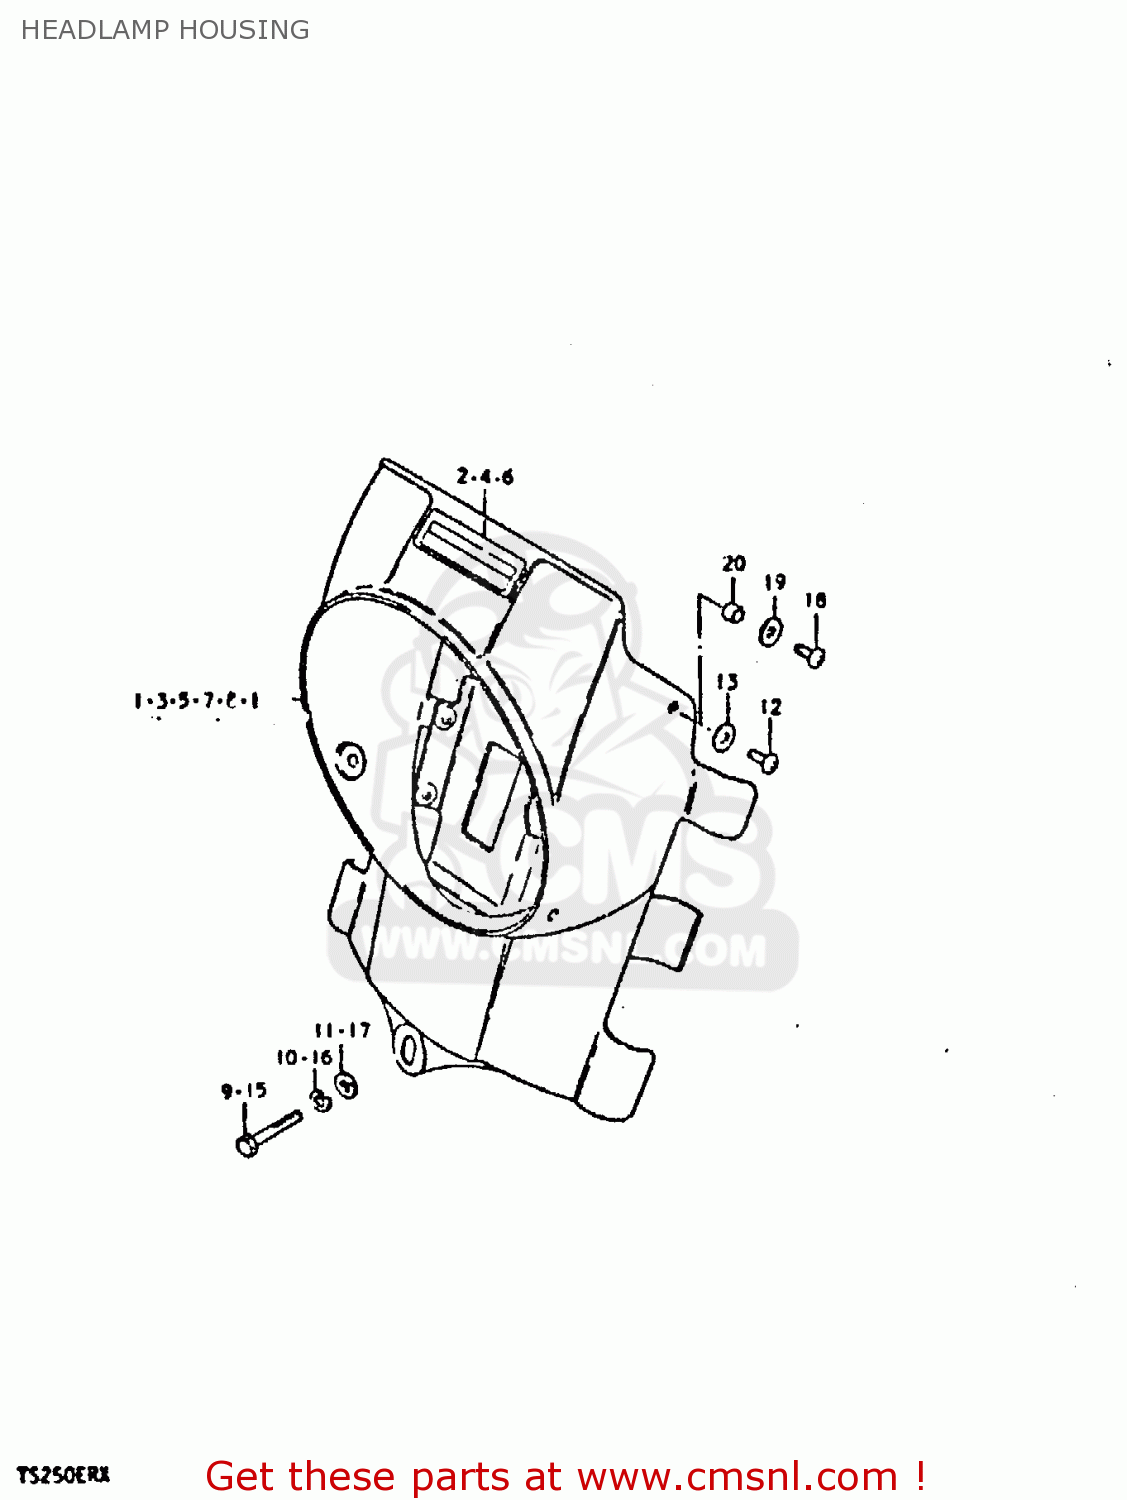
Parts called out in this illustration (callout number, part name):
1	HOUSING, HEADLAMP (RED)
2	TAPE, HOUSING
3	HOUSING, HEADLAMP (YELLOW)
4	TAPE, HOUSING
5	HOUSING, HEADLAMP (WHITE)
6	TAPE, HOUSING
9	BOLT
10	LOCK WASHER
11	WASHER
12	SCREW
13	WASHER (5.5X16X1.2)
14	HOUSING,HEADLAMP
15	BOLT
16	LOCK WASHER
17	WASHER
18	SCREW
19	WASHER (5.5X18X1.6)
20	SPACER (5.5X8X4)
